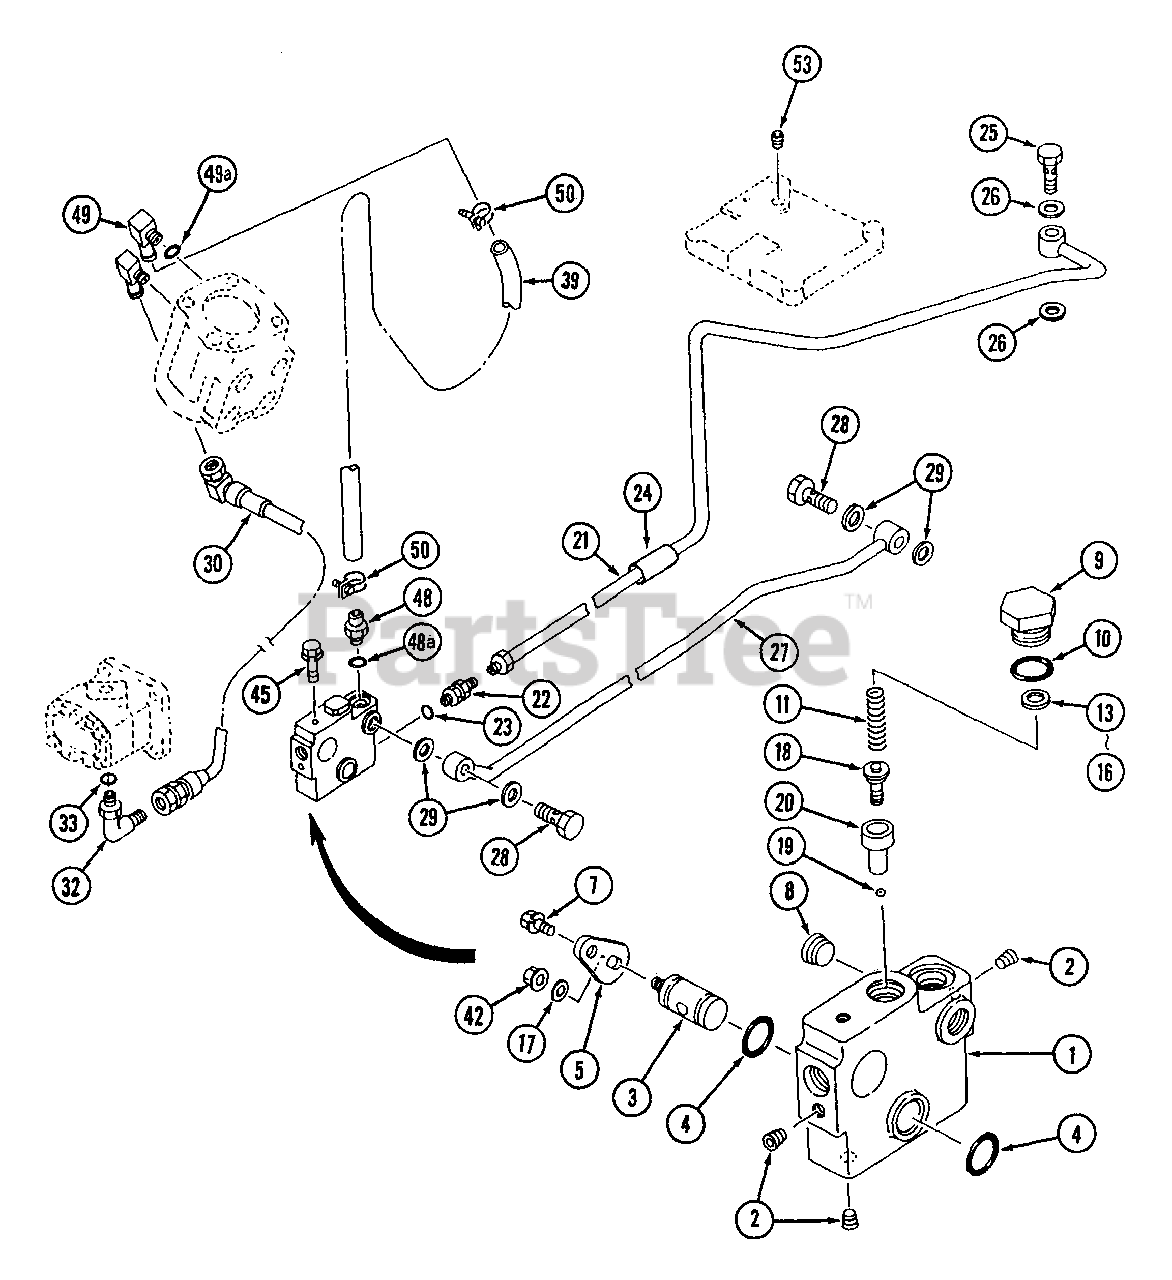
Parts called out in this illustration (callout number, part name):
13	Shim t=0.1
16	Shim t=2.0
19	Ball
20	Relief Housing (NLA)
21	Pipe C Press. Ass'y.
22	Body, (Nipple)
26	Seal Washer
27	Pipe D
29	Seal Washer
32	Adapter
48	Adapter A
49	Adapter
